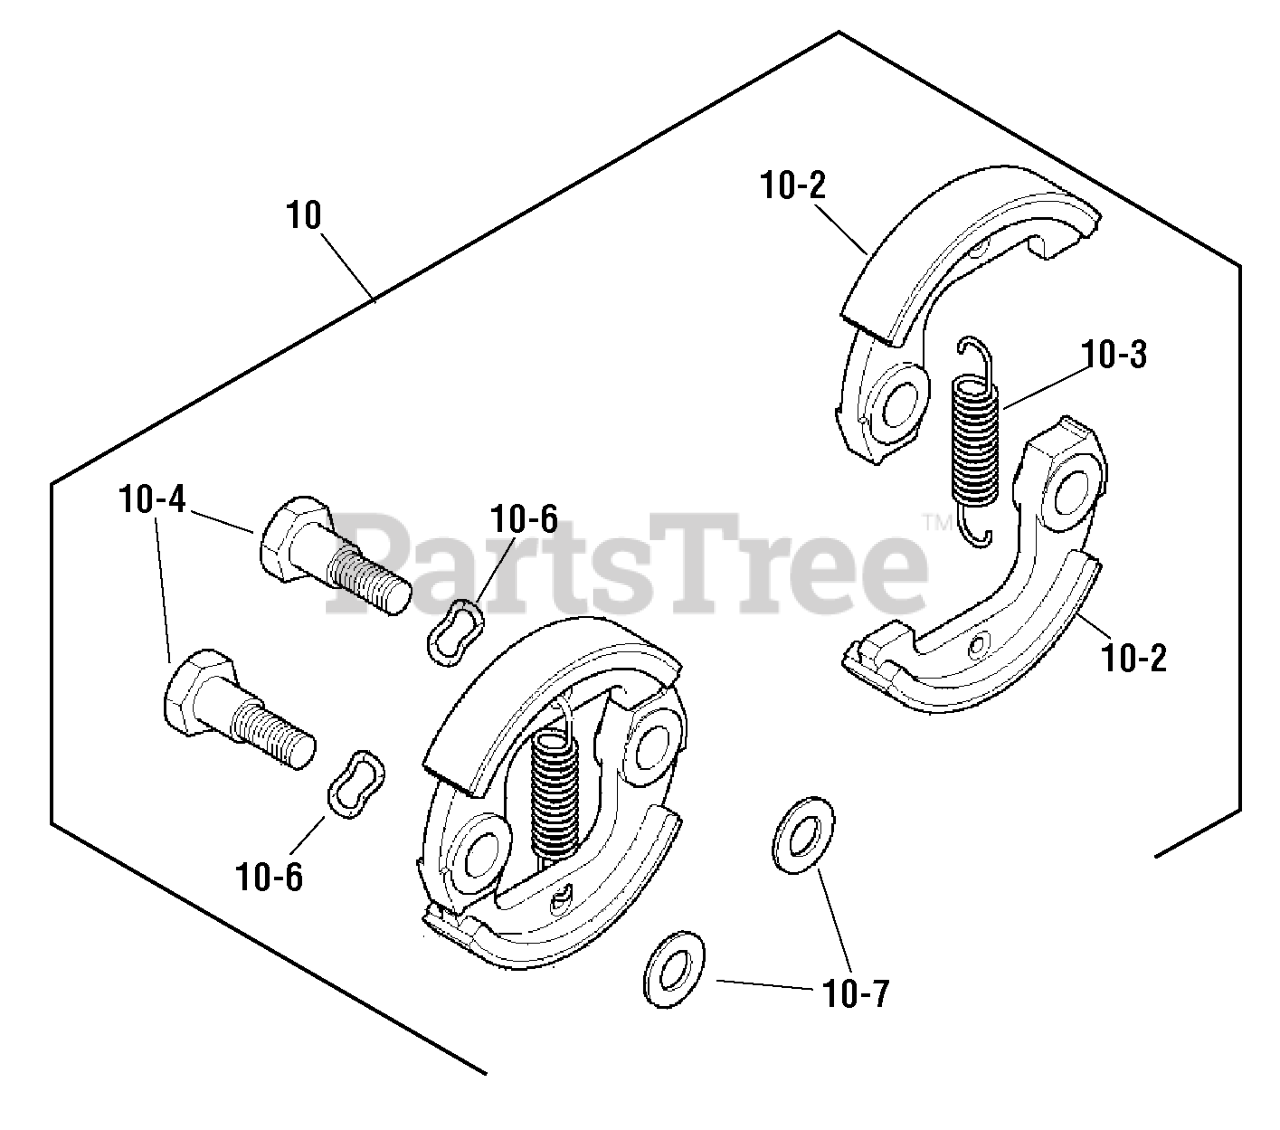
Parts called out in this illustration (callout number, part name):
10	CLUTCH KIT
10-2	SHOE, Clutch
10-3	SPRING
10-4	BOLT, Clutch
10-6	WASHER
10-7	WASHER
